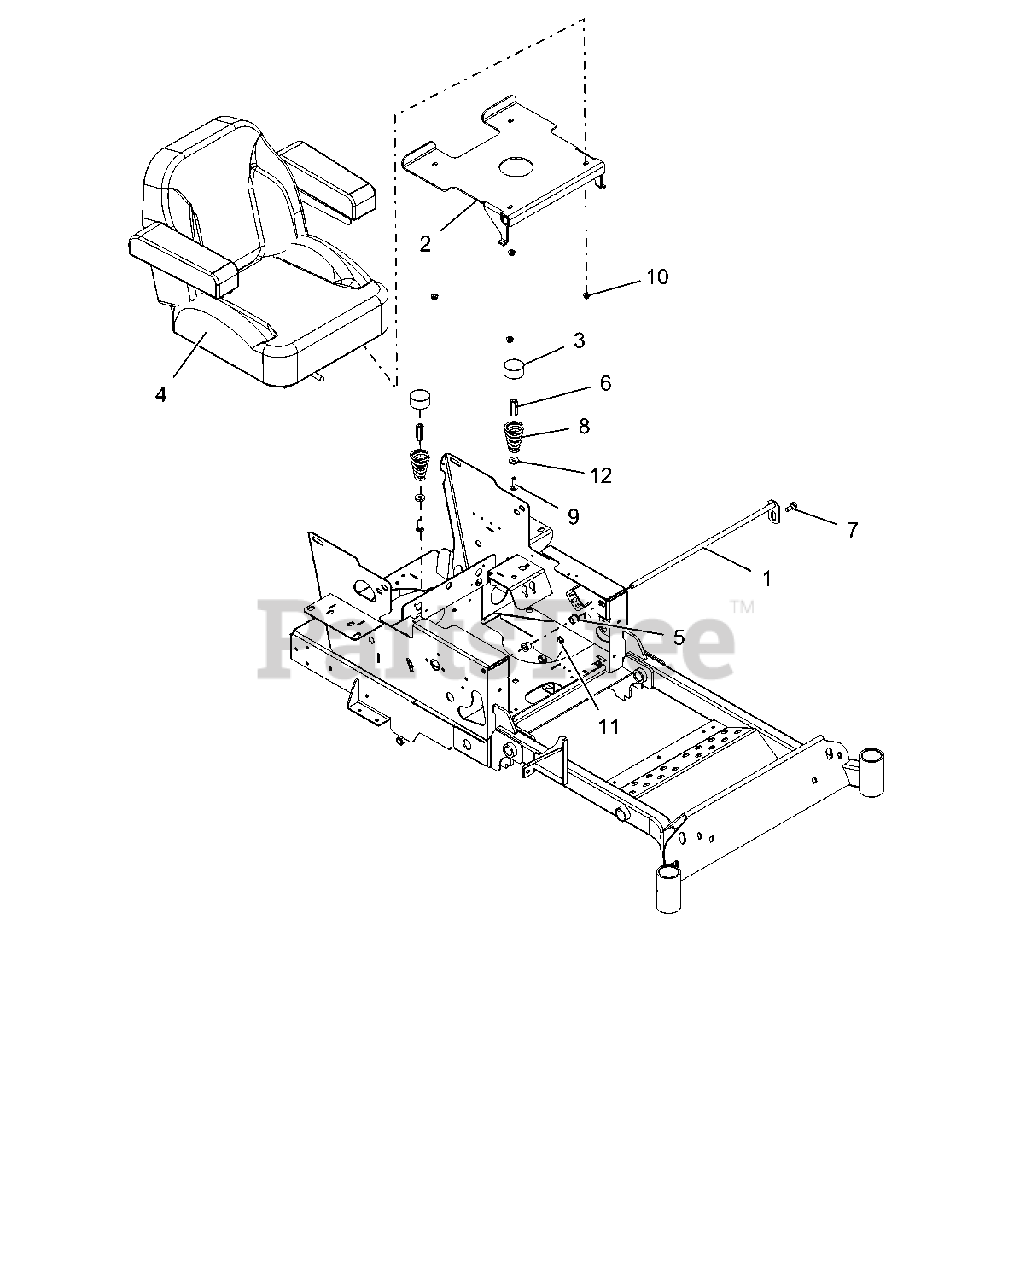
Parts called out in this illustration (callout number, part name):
1	WMT, SEAT SHAFT
2	WLDMT, SEAT PLATE
3	HUB CAP
4	SEAT, SK250 COOL GRAY W/ARMS
5	BSHG, FLG .516X.750X.625X.937
6	NUT COUPLING .375-16X1.75
7	BLT,SHLDR EP .38-16X.30 HEX YZ
8	SPRING, SEAT
9	@BLT-RDHDSQNK .38-16X1.25 G5YZ
10	@NUT-LK-NYL-FLG .31-18 YWZC
11	@NUT-SPNLK-FLG .375-16 YWZC
12	WSHR-FL-STL .406X1.00X.188 YWZ
